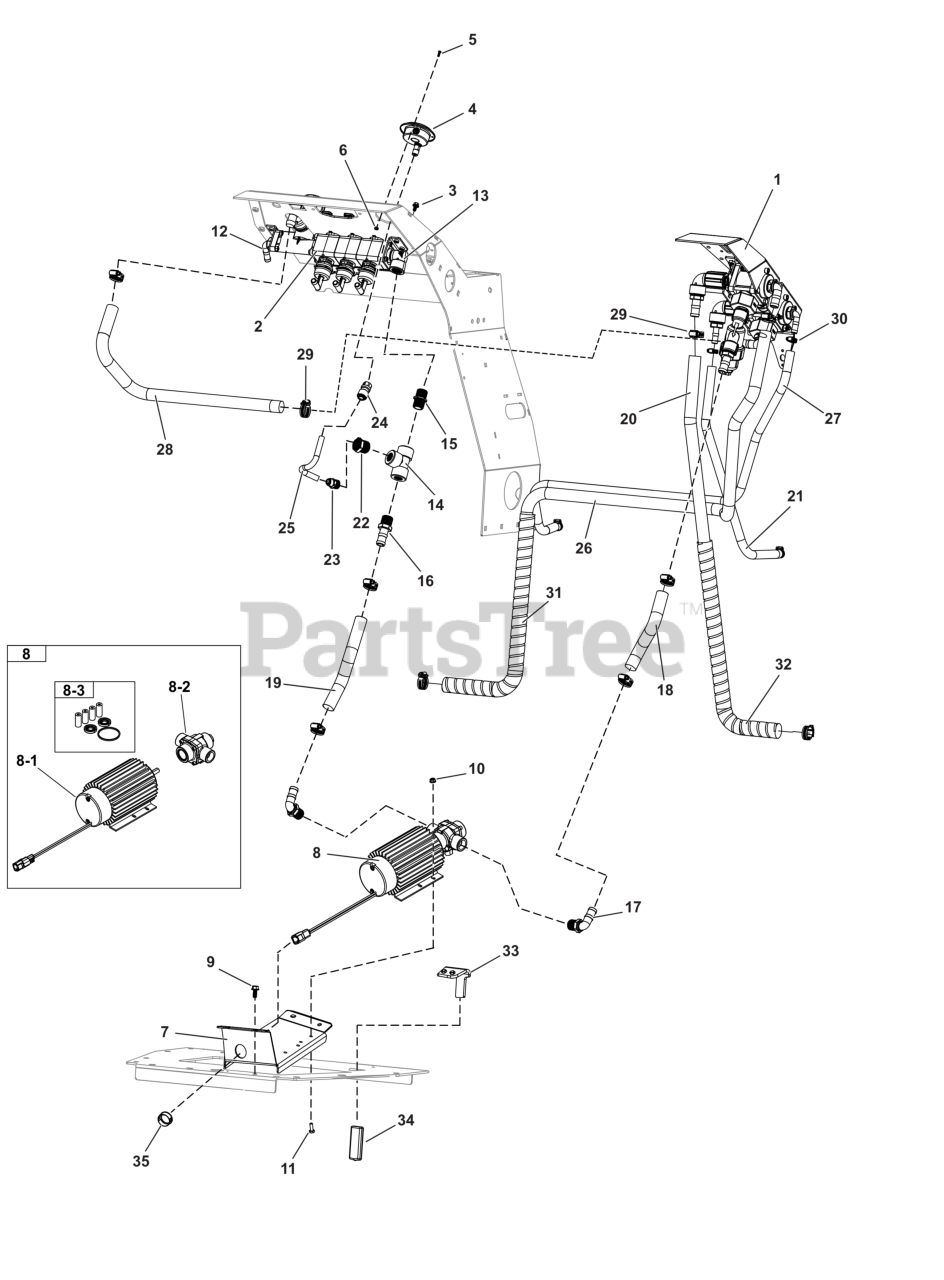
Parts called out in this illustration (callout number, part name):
1	Refer to: Tank Valve Assembly Group
2	MANIFOLD, SPRAY SYSTEM TEEJET
3	SCR-CAP, HSWH .250"-20 X .500" SS188
4	GAUGE, PRESSURE PANEL MOUNT 60 PSI
5	SCR-CAP, SBH #6-32 X .500" SS188
6	NUT-HEX, KEPS #6-32 SS188
7	BRACKET, MOUNT SPRAY PUMP
8	KIT, 9GPM SPRAY PUMP W/CONNECTOR
8-1	MOTOR, PUMP W/ CONNECTOR
8-2	PUMP, ROLLER HYPRO 4001X-4
8-3	KIT, REBUILD PUMP HYPRO 3430-0390
9	SCR-CAP, HSWH .313"-18 X .750" SS188
10	NUT-HEX-NYLK, FLG .250"-20 SS188
11	SCR-CAP, HEX .250"-20 X .750" SS188
12	FTG, ELBW 90° 3/4" MNPT - 1/2" HB BPP
13	FTG, ELBW 90° 3/4"MNPT - 3/4" FNPT BPP
14	FTG, T 3/4" FNPT BPP
15	FTG, CPLR 3/4" MNPT-3/4"MNPT X 1.75" BPP
16	FTG, STR 3/4" MNPT - 3/4"HB BPP
17	FTG, ELBW 90° 3/4" MNPT - 3/4" HB BPP
18	HOSE, CHEM .75" X 8.5"
19	HOSE, CHEM .75" X 9.5"
20	HOSE, CHEM .75" X 48"
21	HOSE, CHEM .50" X 27.5"
22	FTG, STR 3/4" MNPT - 1/2" FNPT BPP
23	FTG, STR 1/2" MNPT - 3/8" PTC BPP
24	FTG, STR 1/4" FNPT - 3/8" PTC BPP
25	HOSE, GAUGE .375" PTC X 5"
26	HOSE, CHEM .75" X 68"
27	HOSE, CHEM .50" X 46"
28	HOSE, CHEM .75" X 23"
29	CLAMP, HOSE, WORM GEAR, 11/16" TO 1-1/4"
30	CLAMP, MINIATURE WORM GEAR MAH6
31	WRAP, HOSE 1.25" ID X 30.0"
32	WRAP, HOSE 1.25" ID X 30.0"
33	ARM, TORQUE ROLLER PUMP
34	GRIP, .188" X 1.00" ID X .150" THK CLSD CELL FOAM
35	BUSHING, SNAP 1" ID
